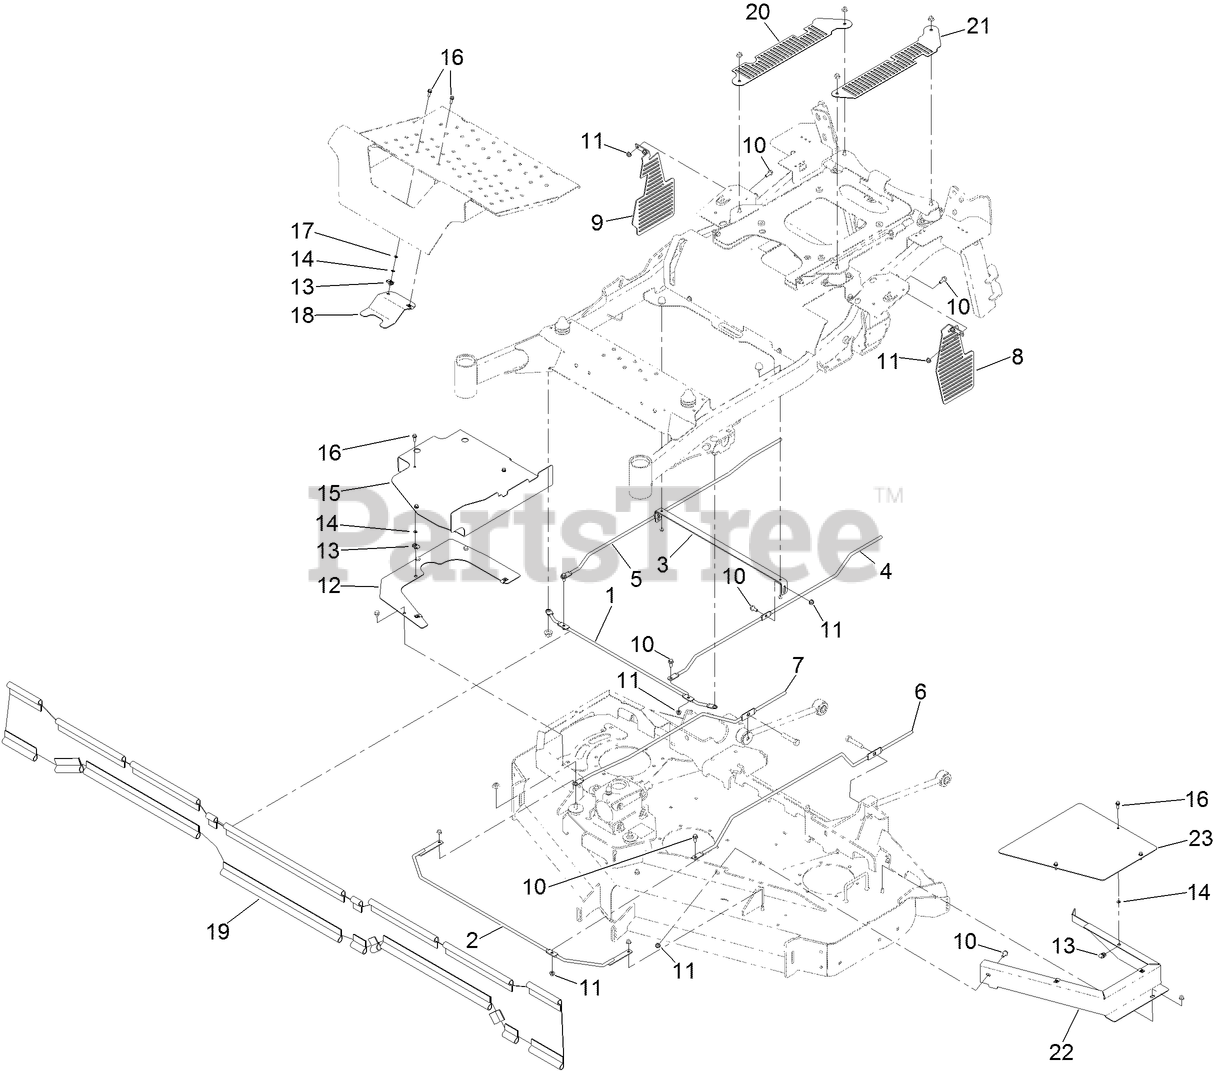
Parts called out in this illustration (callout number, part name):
1	ROD-SUPPORT, UPPER FRONT
2	ROD-SUPPORT, LOWER ASM [WELDED]
3	BRACKET-BRACE
4	ROD-SUPPORT, UPPER LH
5	ROD-SUPPORT, UPPER RH
6	ROD-SUPPORT, LOWER LH
7	ROD-SUPPORT, LOWER RH
8	GUARD-FRAME, LH
9	GUARD-FRAME, RH
10	SCREW-HHF
11	NUT-HF, NI
12	GUARD-PULLEY MOUNT, RH [BLACK]
14	PUSHNUT-RETAINER, BOLT
15	GUARD-PULLEY, RH [BLACK]
16	SCREW-HHF
17	WASHER-FLAT
18	ADAPTER-CAPTIVE
19	GUARD-SKIRT ASM
20	COVER-CE, RH
21	COVER-CE, LH
22	GUARD-PULLEY MOUNT, LH [BLACK]
23	GUARD-PULLEY, LH [BLACK]
